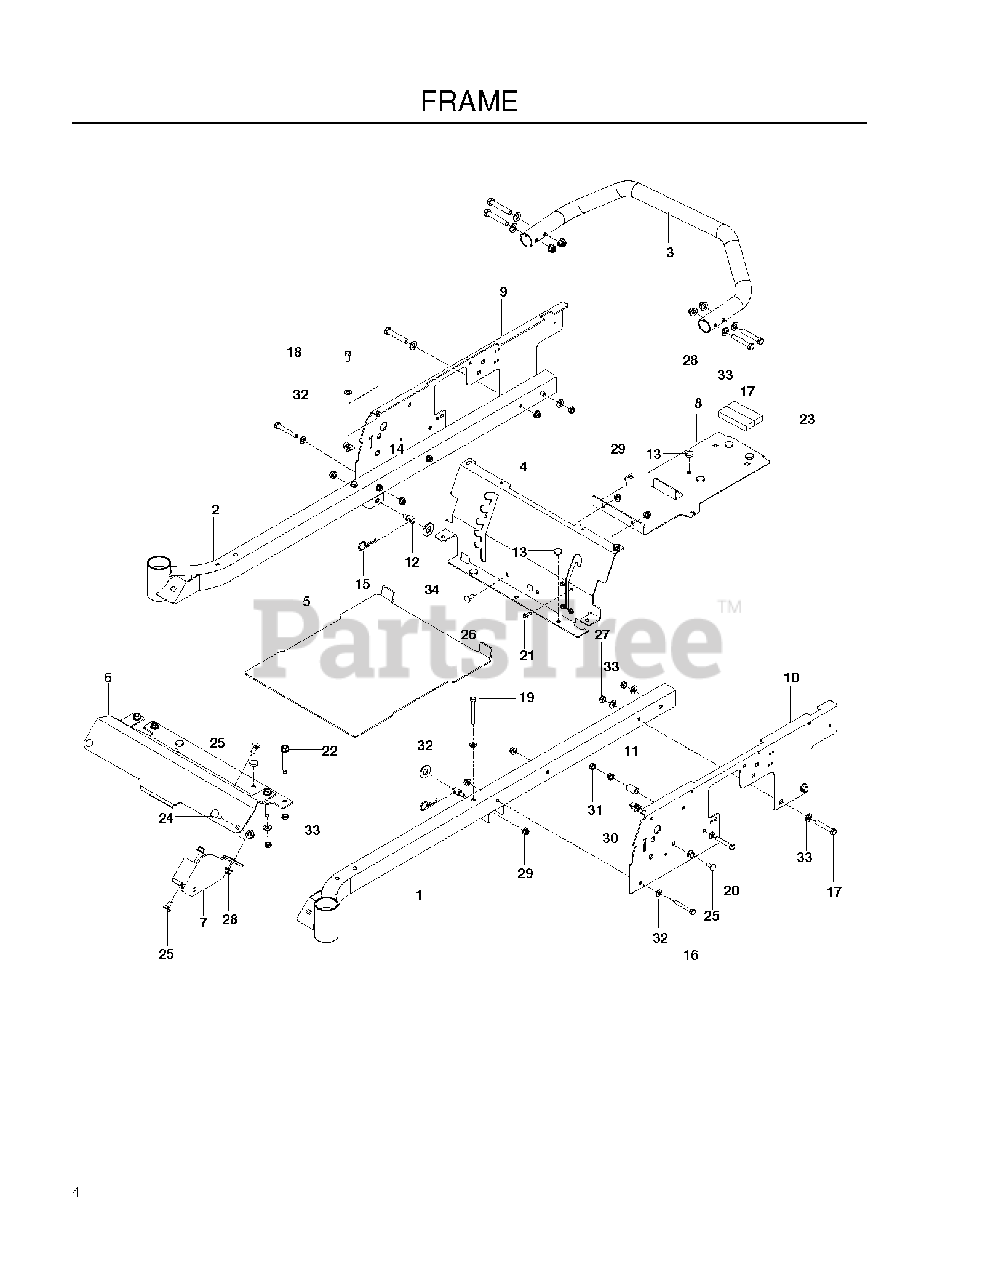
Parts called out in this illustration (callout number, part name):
1	FRAME TUBE, LH, ORG
2	FRAME TUBE, RH, ORG
3	IMPACT BAR, ORG
4	PANEL.SEAT.SUPPORT.ORANGE
5	PAN, FLOOR W/DECALS, HUS
6	FOOT REST, ORG
7	BRACKET, FRONT DECK, BLK
8	SUPPORT, TANK/BATT, BLK
9	PLATE.RH.SIDE.ORANGE
10	PLATE.LH.SIDE.ORANGE
12	STUD.FASTNER.W/ANTI-ROTATE
13	GROMMET, BUMPER
14	U-CLIP 5/16-18 NUT RETAINER
15	HAIRPIN #4
17	HCS 3/8C X 2 1/4
18	HCS 5/16C X 3/4
19	HCS 5/16C X 2-3/4
20	HCS 5/16-18X2
21	SCREW 1/4 X 5/8
22	ENGINE BOLT, SPECIAL
23	FOAM STRIP, FUEL TANK
24	RHSNB 3/8C X 1
25	RHSNB 3/8-16 X 3/4 GR5 ZD
26	BOLT 5/16C X 3/4" CARRIAGE
27	NUT HEX 3/8-16 NYLON, THIN
28	NUT 3/8-16 HEX FLG NYLOC ZD
29	5/16-18 NYLOC FLANGE NUT
30	NUT 5/16C WHIZ
31	NUT 5/16 NYLOC
32	FLAT WASHER 5/16 SAE
33	WASHER 3/8 SAE FLAT
34	WASHER 5/8 FLAT
